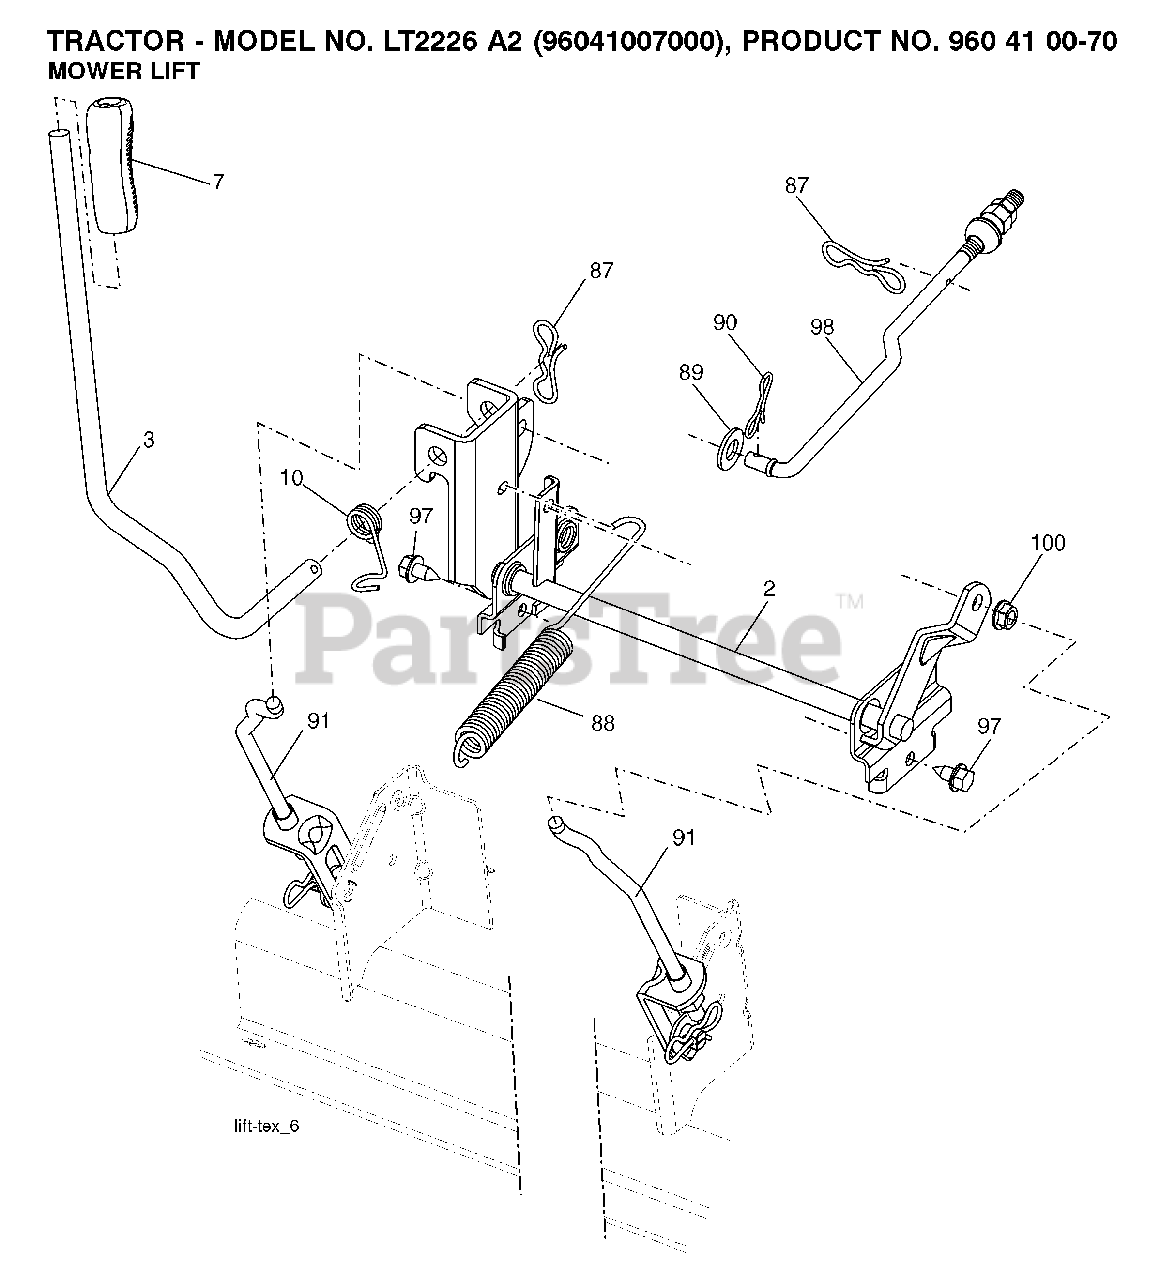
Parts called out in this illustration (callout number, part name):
2	SHAFT.ASM.LIFT.CROSS.H
3	LEVER.LIFT.HANDLE.GT
7	GRIP.HANDLE.LIFT.PVC.BLACK
10	SPRING.TORSION.LIFT.HANDLE
87	PIN.COTTER.7/16.BOW TI
88	SPRING.LIFT.ASSIST
89	WASHER.CLEAR.ZINC
90	PIN.COTTER.5/16.BOW TI
91	LINK.ASM.LIFT.REAR
97	SCREW, 3/8-16X3/4
98	LINK.ASM.SUSP.FRONT.MW
100	LOCKNUT
